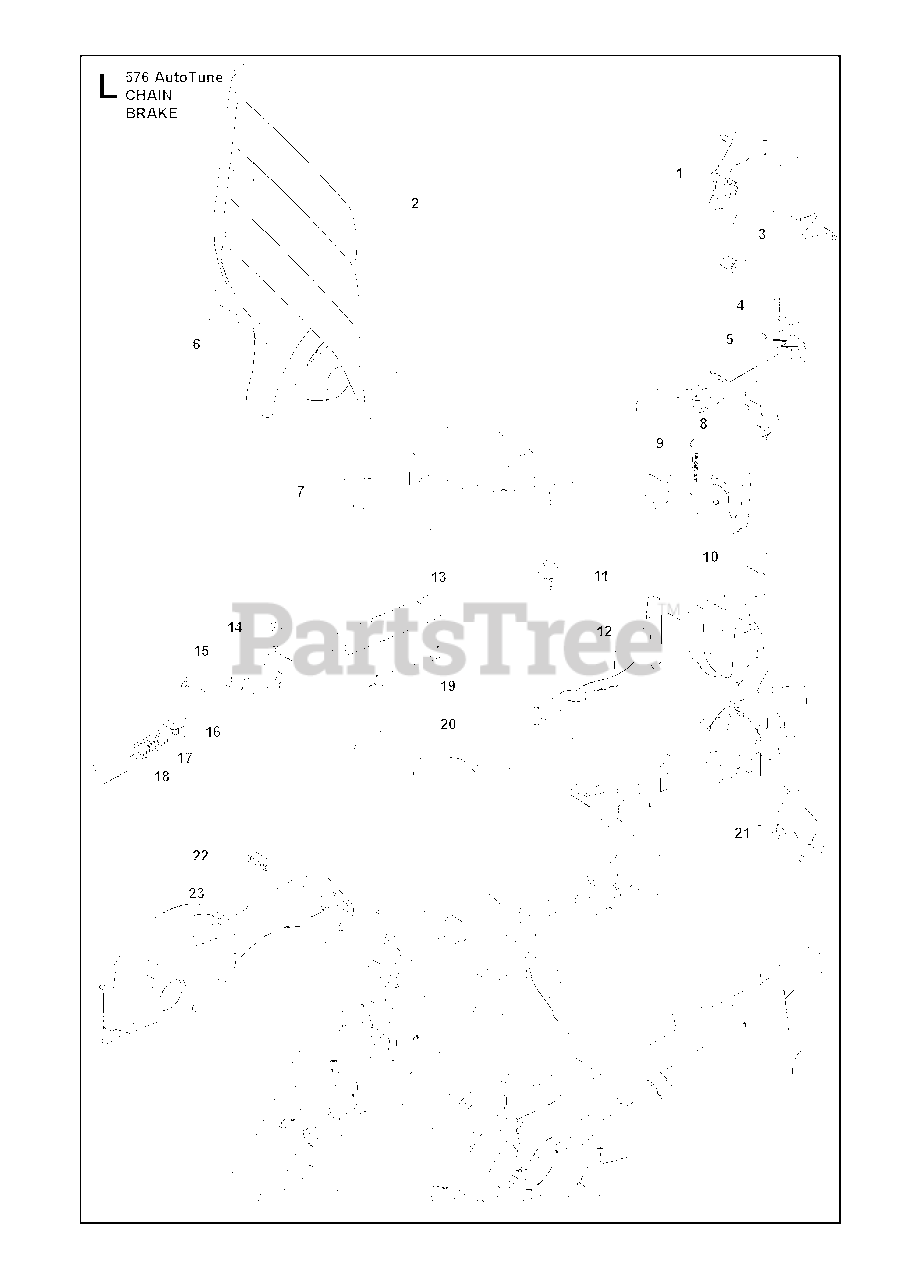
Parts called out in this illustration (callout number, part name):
2	CHAIN BRAKE
5	CHOKE CONTROL
13	BRAKE SPRING
15	KNEE JOINT
17	LOCK SPRING
19	%SUPPORT
20	BRAKE BAND
